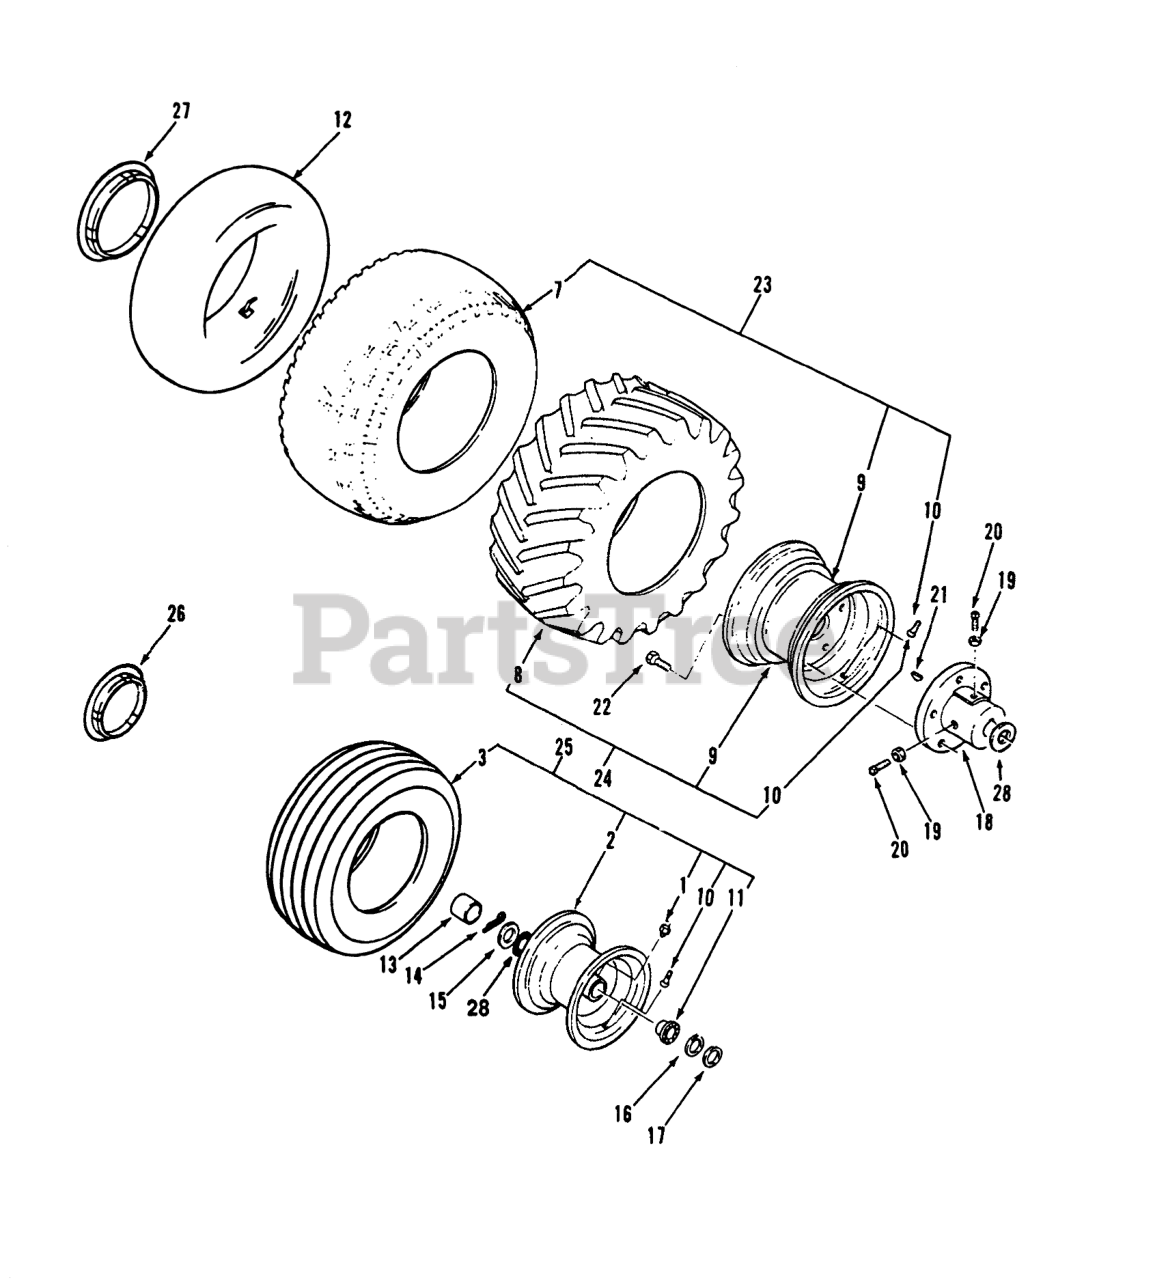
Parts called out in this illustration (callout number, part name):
1	ZERK-GREASE
2	Rim-Front
3	Tire (16 x 6.5-8) 2-Ply -2 Wheel Axel
7	TIRE
8	Tire-Cleat, Rear
9	WHEEL
10	VALVE
11	BEARING-WHEEL
12	TUBE-INNER
13	HUBCAP
14	PIN-COTTER
15	WASHER WHEEL
16	WASHER
17	WASHER-SHIM
18	Hub Rear
19	NUT-JAM
20	SCREW-SET, SQH
21	KEY-WOODRUFF
22	Lug Nut
23	ASM-Wheel& Tire
24	ASSY WHEEL & TIRE
25	Tire Assy-Front Wheel
26	6"-HUB CAP LOGO
27	12"-HUB CAP LOGO
28	WASHER-THRUST
